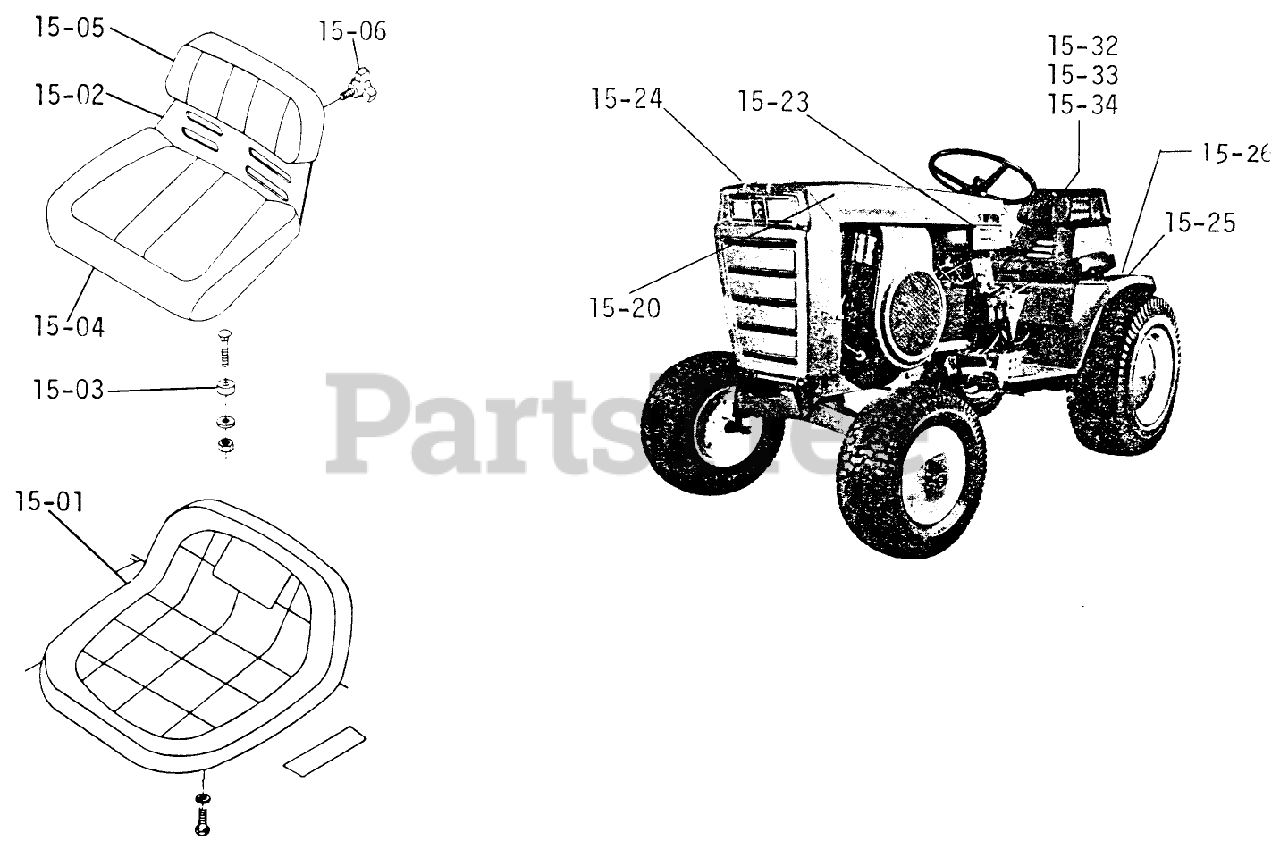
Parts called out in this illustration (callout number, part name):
15-04	BULLT 281
15-05	BULLT 281
15-26	Reflector
15-36	Decal
15-37	Decal Free Wheeling
15-38	Decal
